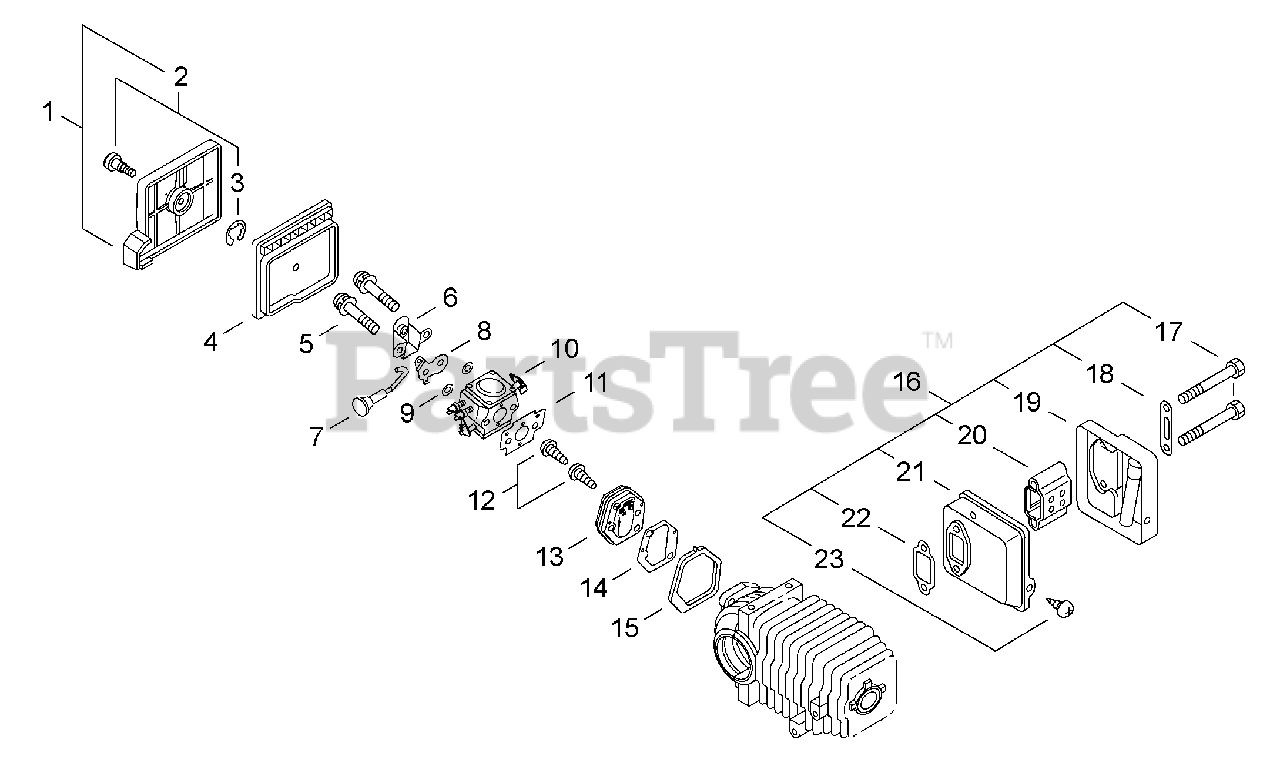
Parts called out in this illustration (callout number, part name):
1	COVER ASSY, AIR FILTER
2	THUMBSCREW
3	E-RING 4
4	FILTER, AIR
5	SCREW 5×45
6	PLATE, PREVENT
7	ROD, CHOKE
8	SHUTTER, CHOKE
9	WASHER 5.5×8×0.8
10	CARBURETOR - WT-385A
11	GASKET, INTAKE
12	SCREW 5×18
13	INSULATOR KIT
14	GASKET, INTAKE
15	SEAL, INTAKE
16	MUFFLER ASSY
17	BOLT 6 MM
18	PLATE, EYE
19	COVER, MUFFLER
20	SILENCER
22	GASKET, MUFFLER
23	SCREW TAPPING 4×8
